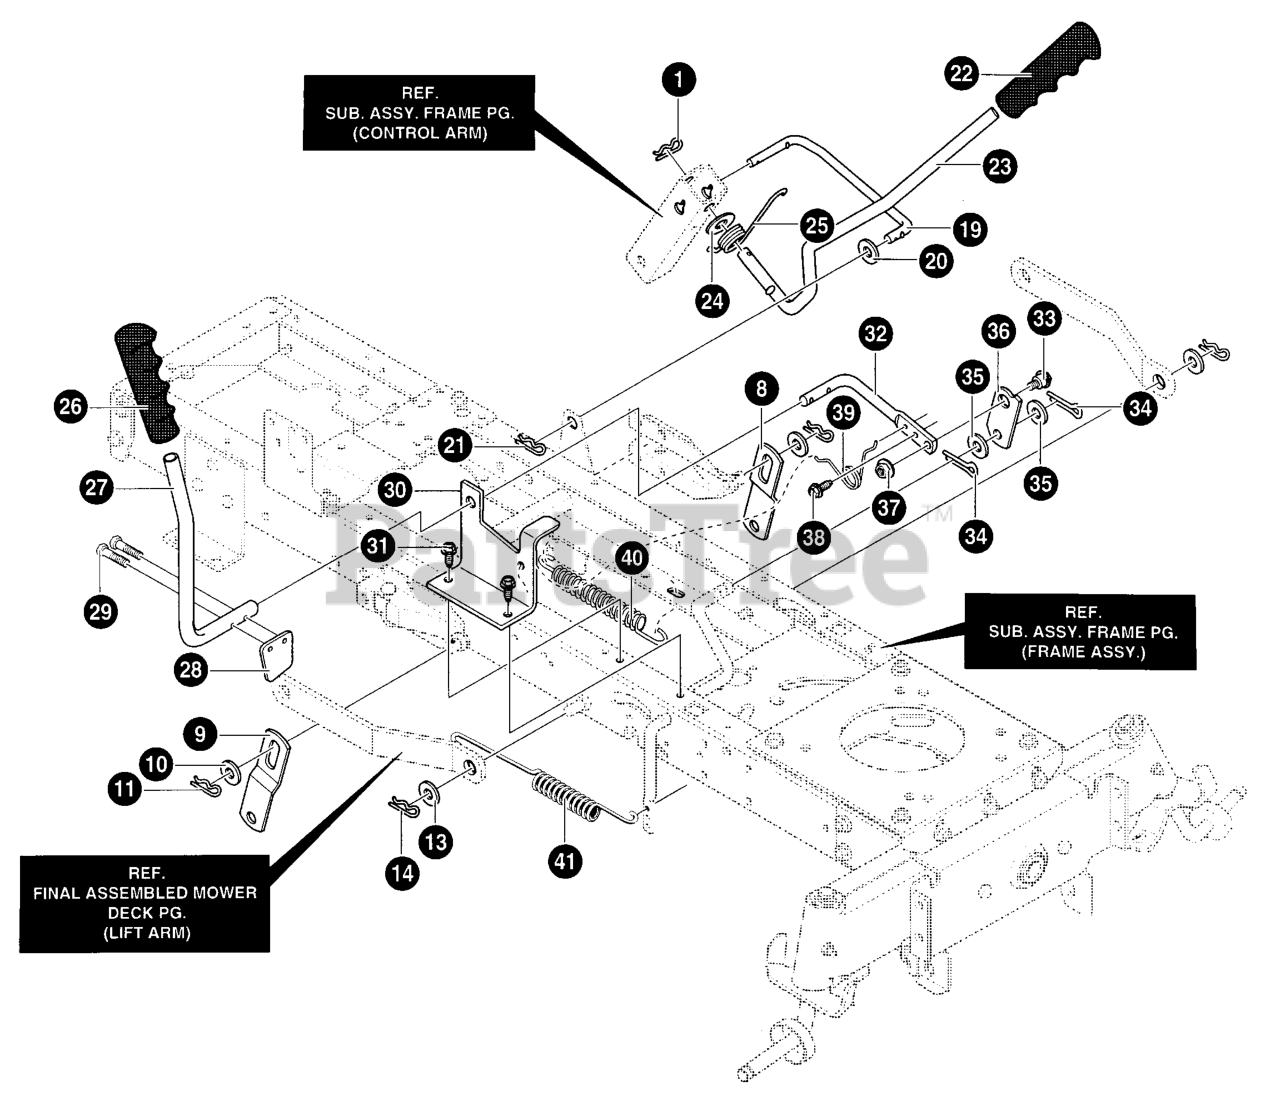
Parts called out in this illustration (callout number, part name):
1	HAIR PIN
8	LINK, LIFT LH
9	LINK- LIFT
10	FLATWASHER
11	PIN, HAIR
13	WASHER, FLAT
14	PIN, HAIR
19	LINK LIFT HANDLE
20	WASHER, FLAT
21	PIN, HAIR
22	GRIP, LIFT
23	HANDLE, LIFT
24	WASHER, FLAT
25	TORSION SPRING
26	GRIP, PTO
27	PTO LEVER
28	PADDLE, SWITCH
29	Screw, Hex
30	BRACKET, PTO
31	BOLT, 5/16-18X.5
32	LEVER, PTO
33	BOLT,.50X.75
34	PIN, HAIR
35	WASHER, FLAT
36	LINK PTO
37	NUT, 3/8-16
38	SCREW, 5/16-18 x 0.75
39	TORSION SPRING
40	SPRING, TENSION
41	EXTENSION SPRING
